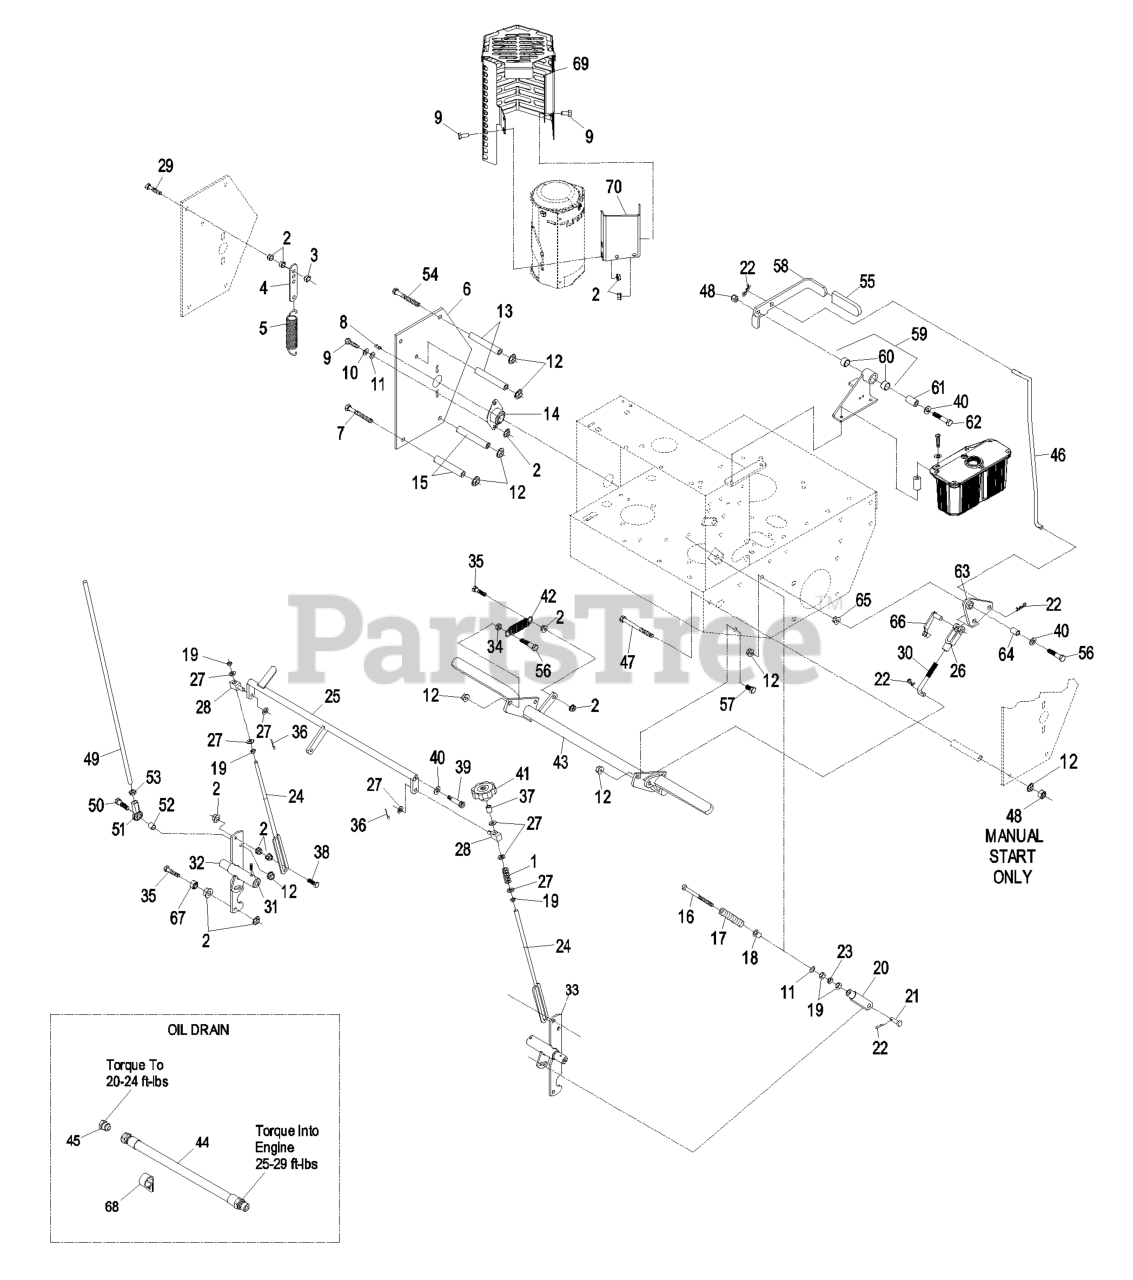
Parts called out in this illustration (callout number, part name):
1	SPRING-COMPRESSION
3	NUT-LOCK, NI
4	TAB-SPRING, EXTENSION
5	SPRING-EXTENSION
6	SHIELD-CONTROL
7	SCREW-HH
8	FITTING-GREASE
9	SCREW-HH
10	WASHER-LOCK
11	WASHER-FLAT
12	NUT-HHF, WHIZ
13	SPACER-SHIELD
14	BEARING-FLANGE, SIDE
15	SPACER-SHIELD
16	BOLT-RETURN, NEUTRAL
17	SPRING,COMPRESSION (NEUT)
18	BUSHING-FLANGED
19	NUT-HEX
20	YOKE-ADJUSTABLE
21	PIN-CLEVIS
22	PIN-COTTER
23	NUT-JAM
24	LINK-CONTROL, SPEED
25	CRANK-CONTROL, SPEED
26	YOKE-LINKAGE, BRAKE
27	WASHER-PLAIN
29	BOLT-TAP, HH
30	LINKAGE-LOWER
31	SCREW-SET
32	SHAFT-CONTROL, LH
33	SHAFT-CONTROL, RH
34	NUT-JAM
35	SCREW-HH
36	PIN-COTTER
38	SCREW-HH
39	SCREW-HSH
40	WASHER-FLAT
41	KNOB-TRACKING
42	SPRING-IDLER
46	LINKAGE,UPPER- TTHP
47	SCREW-HH
48	NUT-LOCK, NI
49	LINK,DRIVE (PLTD)
50	SCREW-HH
51	JOINT-BALL END, LH
52	SPACER-TUBE, PUMP LINK
53	NUT-HEX JAM, LH
54	SCREW-HH
55	GRIP-LEVER
56	SCREW-HH
57	SCREW-HH
58	LEVER,PARK BRK W/DECAL
59	BRACKET ASM
60	SLEEVE-BUSHING
61	BUSHING-PIVOT
62	SCREW-HH
63	BELLCRANK ASM
64	BUSHING-PLASTIC
66	PIN-SPRING, CLEVIS
67	NUT-JAM
68	CLIP-LOOM
69	MUFFLER SHIELD ASM
70	BRACKET-MUFFLER
